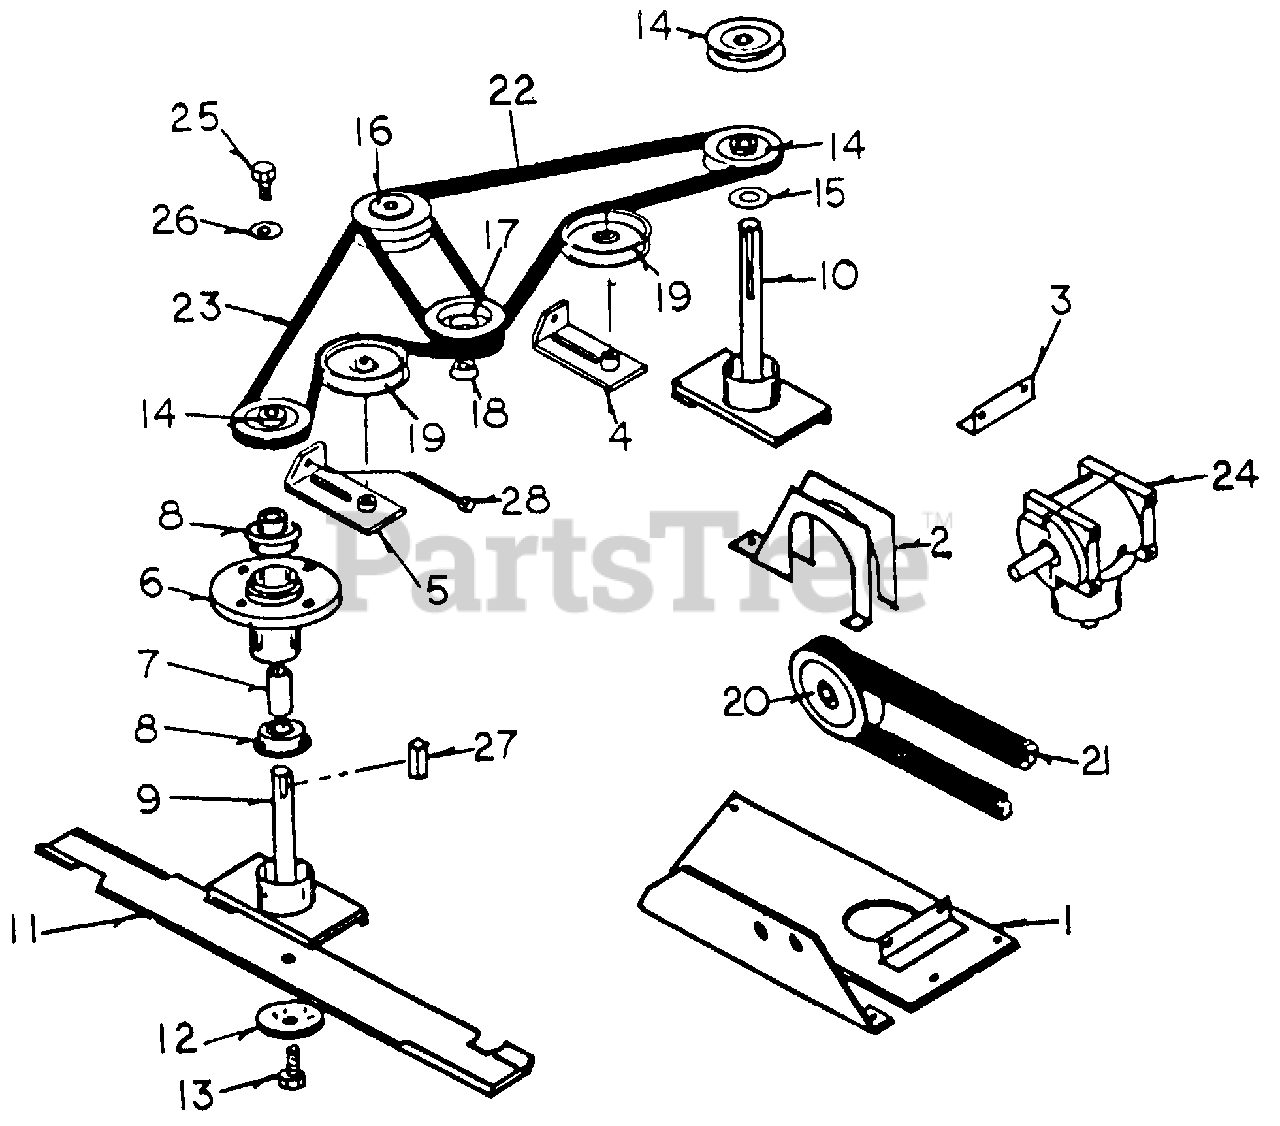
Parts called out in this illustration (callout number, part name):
2	Belt Guard
3	Gearbox Mount Angle
4	Belt Tightener
5	Belt Tightener
6	Spindle Housing
7	Spindle Spacer
8	Spindle Bearing
9	Spindle Shaft
13	Hex Bolt, 3/8-24 x 1-1/4"
14	Spindle Pulley
16	Spindle Pulley, Double A
17	Gearbox Pulley, Out Put
18	Hub
20	Gearbox Pulley, In Put
21	Deck Drive Belt
22	Deck Belt
25	Hex Bolt, 5/6-24 x 3/4"
26	Washer, 5/16", 10 Ga.
27	Key Stock, 3/16"
28	Adjustment Bolt
